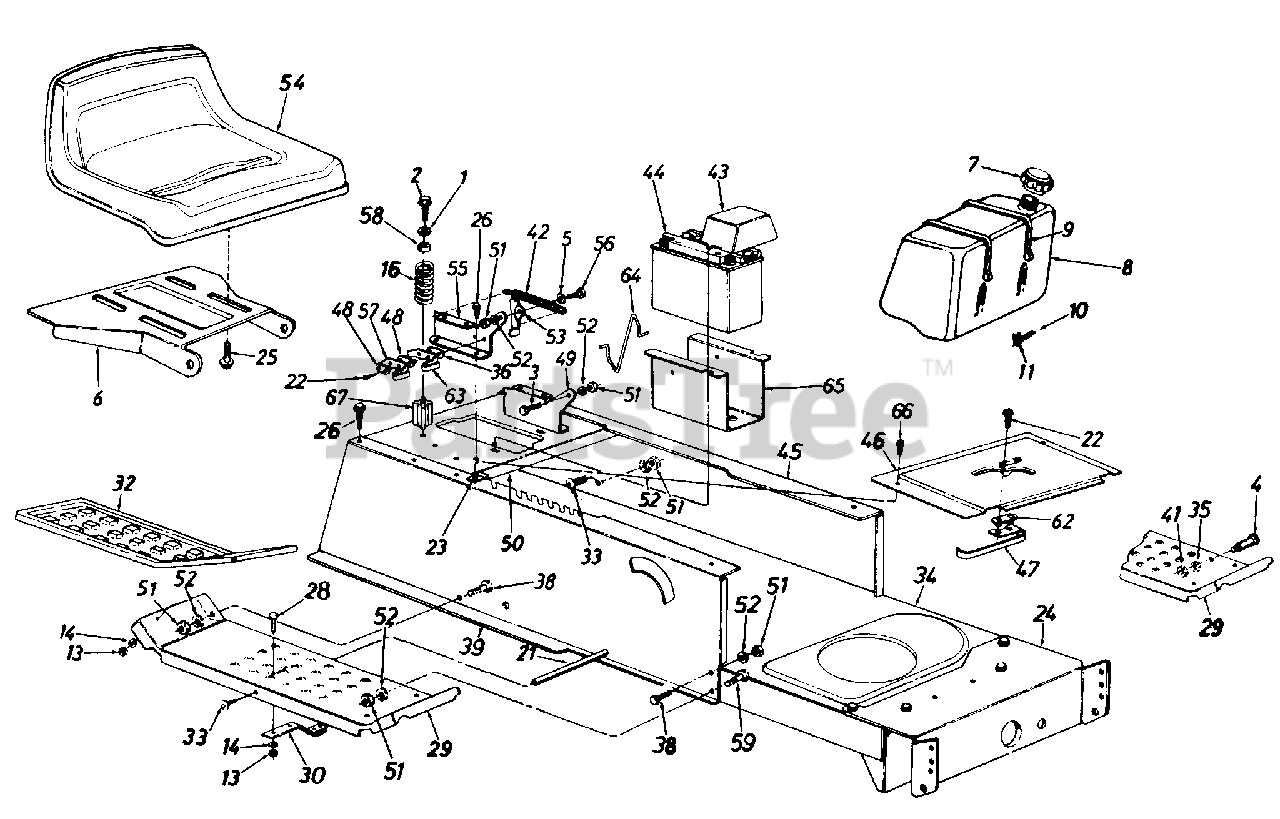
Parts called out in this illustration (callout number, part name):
1	Fl-Wash. .344" I.D. x .875"
2	Hex Wash. Hd. Tap Scr. 5/16-18 x 3.25" Lg.
3	Shld. Bolt .437" Dia. x .162"
4	Shld. Bolt .50" Dia. x .84"
5	Spr-Wash. .445" l.D. x .75
6	Seat Pivot Bracket
7	Fuel Cap
8	Fuel Tank
9	Tie Strap
10	Fuel Line
13	Hex Nut 1/4-20 Thd.
14	L-Wash. 1/4" l.D.
16	Compression Spring
21	Running Board Rod
22	Hex Wash. Hd. AB-Tap Scr. #8 x .50" Lg.
23	Speed Nut #10Z
24	Front Pivot Brkt.
25	Hex Tap Scr. 3/8-16 x .75"
26	Hex Wash. Hd. AB-Tap Scr. 5/16 x .75" Lg.
28	Carriage Bolt 1/4-20 x .62"
29	Running Board
30	Blade Brake Ass'y.
32	Rubber Foot Pad-L.H.
33	Truss Mach. Scr. 5/16-18 x .75n Lg.
34	Lower Frame
35	L-Wash. 3/8" I.D.
36	Insulator Boss Plate
38	Hex Bolt 5/16-18 x .75" Lg.
39	483/N Upper Frame-R.H.
41	Hex Nut 3/8-16 Thd.
42	Extension Spring 5.3l" Lg.
43	Battery Cover
44	12-V Battery
45	Upper Frame-L.H.
46	Shift Cover
47	Reverse Safety Switch
48	Insulator Plate
52	L-Wash. 5/16" I.D.
53	Seat Lift Brkt.
54	Seat
56	Shld. Bolt .437" Dia. x .268"
57	Spring Switch
59	Hex Wash. TT-Tap Scr. 5/16-18 x 7/8" Lg.
62	Insulator Nut Plate
63	Safety Switch
64	Battery Tray Clip
65	Battery Tray
66	Truss Mach. B-Tap Scr. #10 x .5" Lg.
67	Spring Spacer
